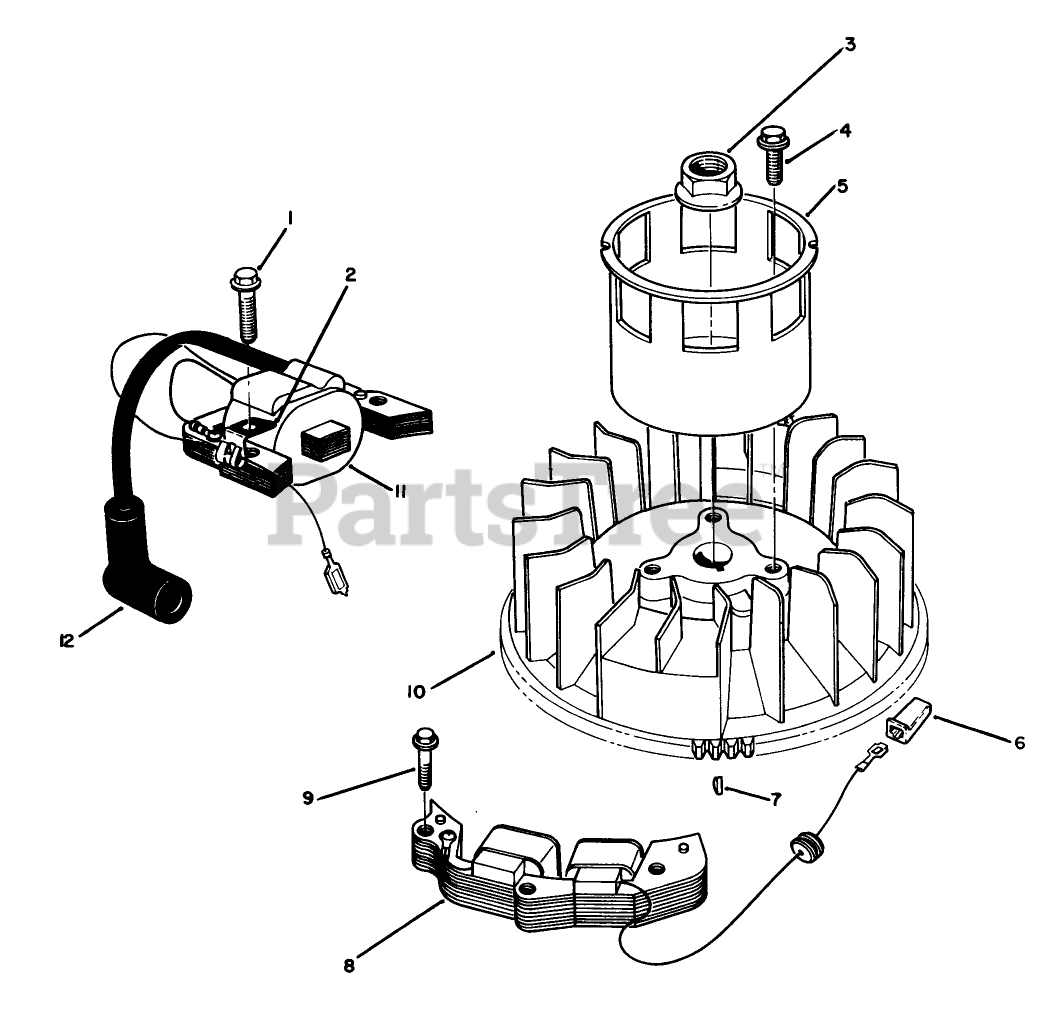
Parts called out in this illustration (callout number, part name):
2	CLAMP
6	CONNECTOR BODY
10	FLYWHEEL
11	COIL
12	COVER
